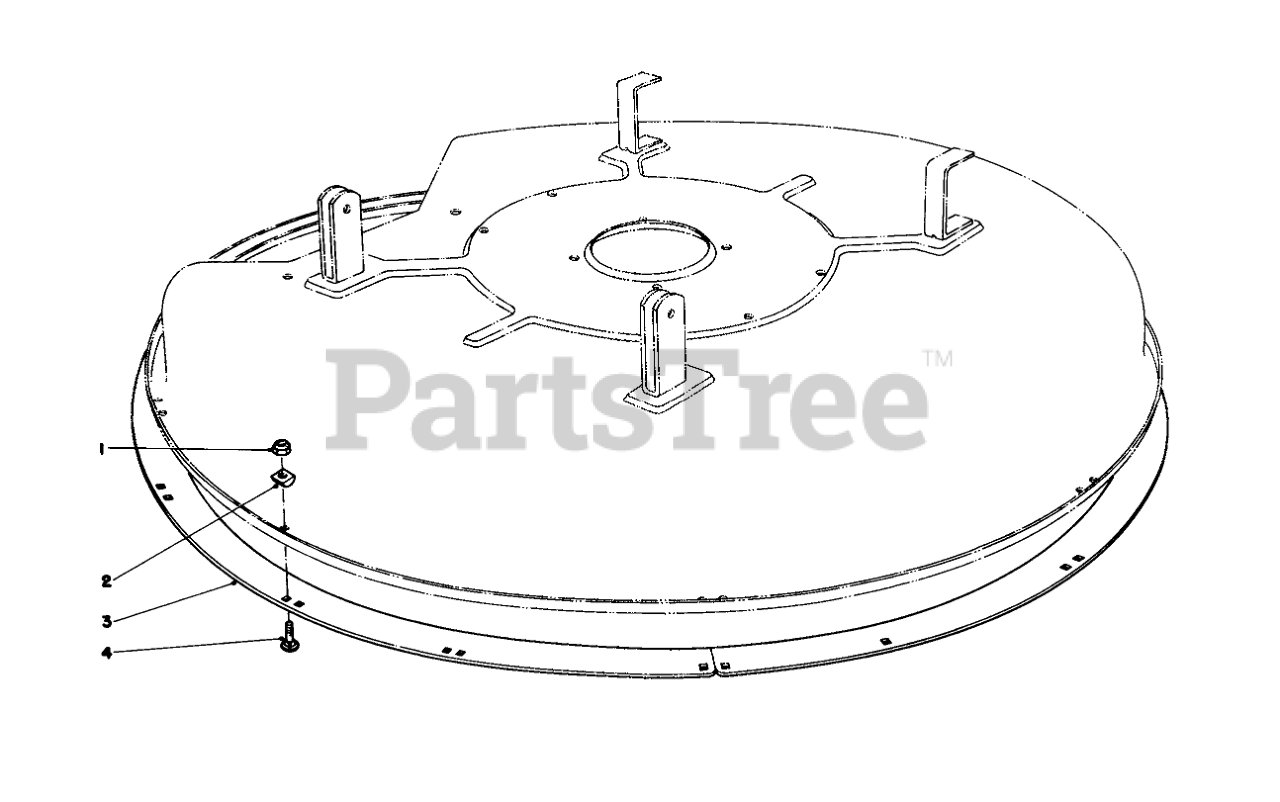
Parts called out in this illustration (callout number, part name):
1	NUT-LOCK, NI
2	Spacer-Deck Ring
3	DECK RING B
4	BOLT-CARR
